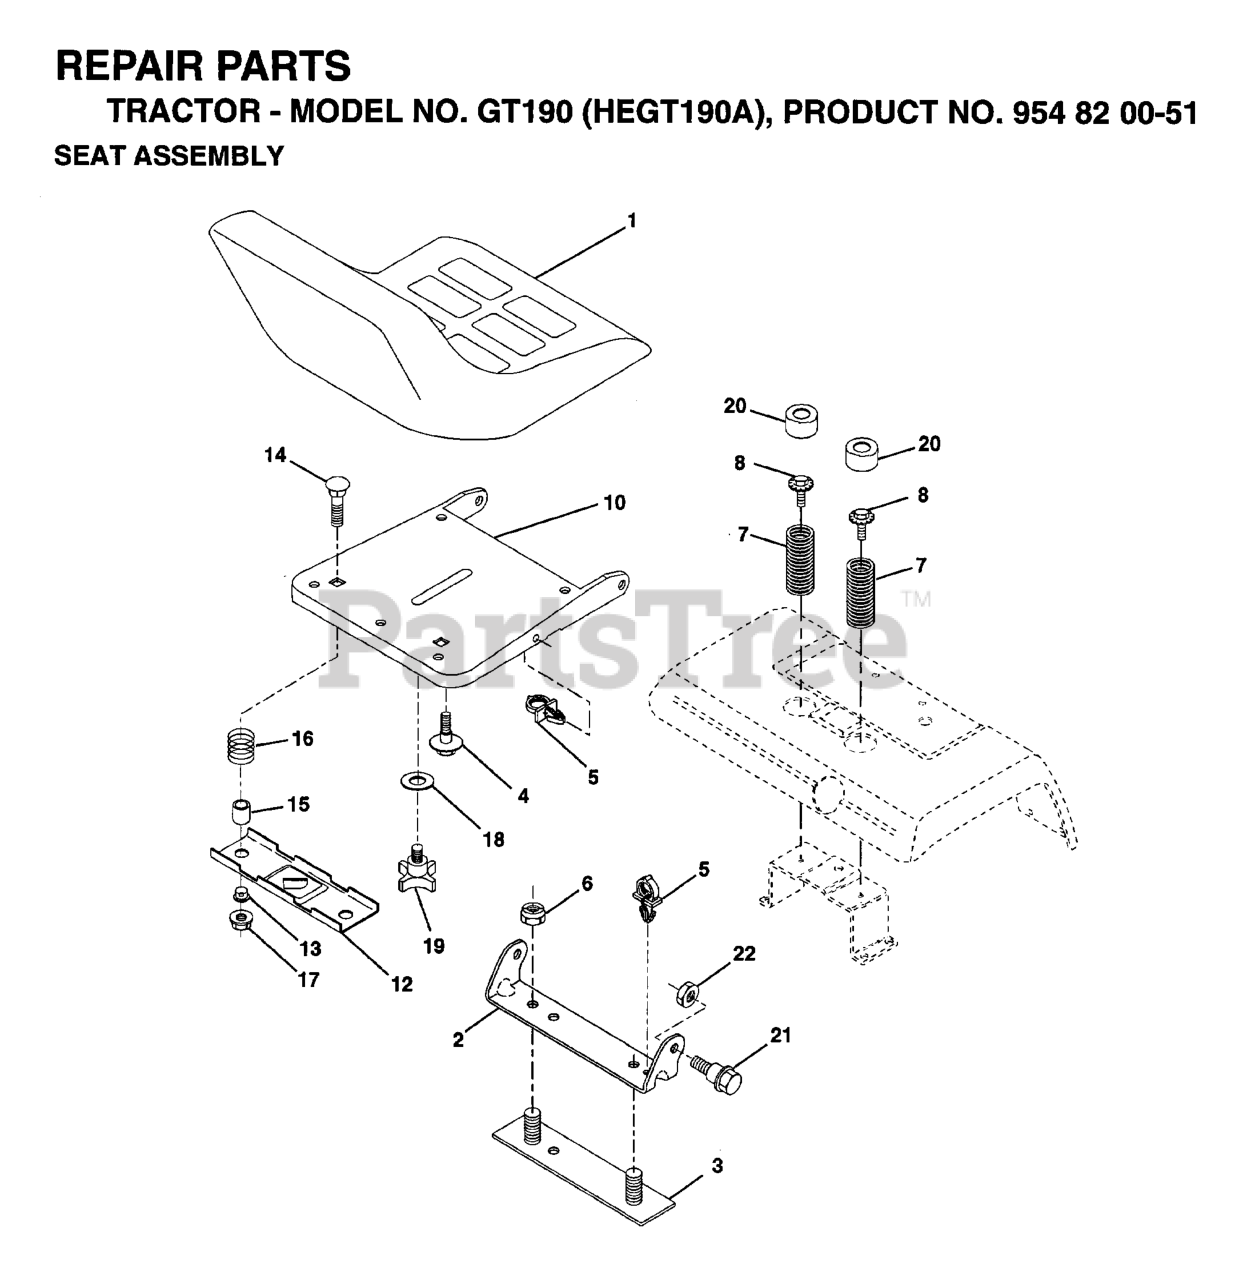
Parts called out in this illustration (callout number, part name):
1	SEAT
2	SEAT PIVOT BRKT
3	STRAP
4	BOLT,SHOULD
6	NUT
7	SPRING COMPRESSION
8	Screw 5/16-18 x 1/2 Hex, Self Tapping 5/16-18 x 1/2
9	WASHER
10	SEAT PAN
12	BRKT SWITCH
14	Bolt Rdhd. Sht. Nk 1/4-20 x 1-3/8
15	SPACER SPLIT
16	SPRING COMPRESSED
17	NUT T
19	KNOB 1/2" YT
20	CAP SPRING
21	BOLT.SHOULDER.5/16-18
22	LOCKNUT
